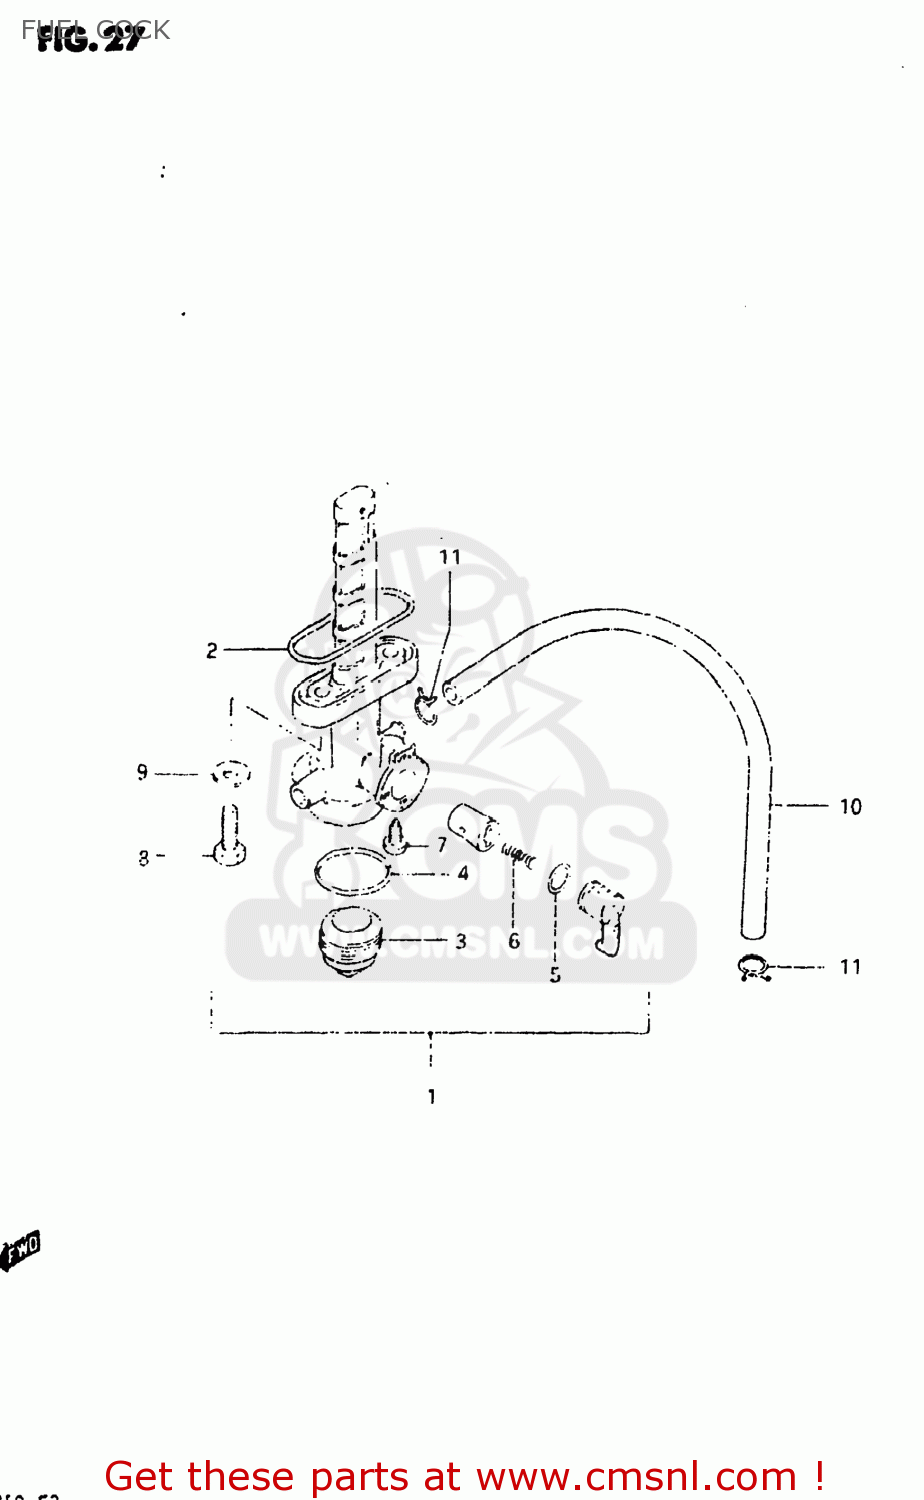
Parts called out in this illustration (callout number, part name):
1	COCK ASSEMBLY,FUEL
2	O RING,FUEL COCK
3	CUP,STRAINER
4	GASKET,FILTER (NAS)
5	O-RING
6	SPRING
7	SCREW
8	BOLT(6X20)
9	GASKET
10	HOSE
11	CLIP
